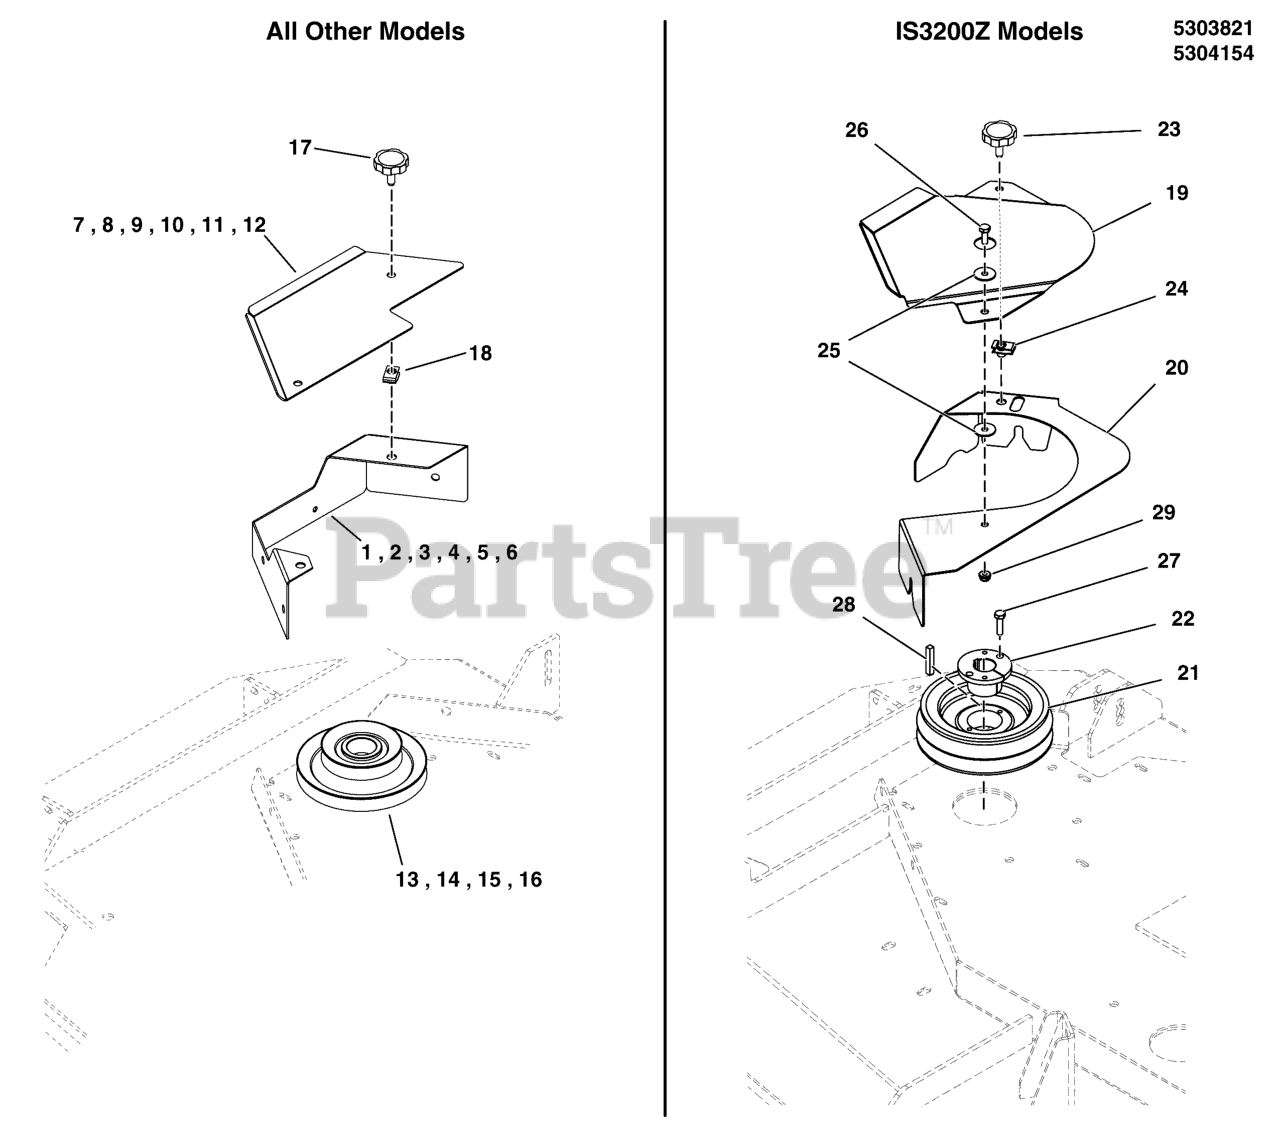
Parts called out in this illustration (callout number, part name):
1	GUARD, DECK, 61", TURBO-PRO - BLK
2	GUARD, DECK, 61/200XT, FASTVAC - BLK
3	WELD, DECK GUARD, COMM BLWR - BLK
4	GUARD, DECK, 2100-52" - BLK
5	GUARD, DECK 48/52 - BLK
6	WELD, PULLEY GUARD, 800-61, BLOWER - BLK
7	PLATE, TOP GUARD, 61" - BLK
8	GUARD, BELT, 61", 2000 FASTVAC - BLK
9	BELT SHIELD, 61" COMM BLWR - BLK
10	PLATE, TOP GUARD, 2100-52" - BLK
11	PLATE, TOP GUARD, 52 - BLK
12	SHIELD, BELT, 800-61, BLOWER - BLK
13	DOUBLE PULLEY, DECK, 61" TP
14	PULLEY, DOUBLE, DH4600, 5.95 OD TAPERED
15	PULLEY, DOUBLE, 52" DECK
16	DOUBLE PULLEY, DECK, 800-61", T-MAX
17	KNOB, 5/16-18 X 1.00, ROSETTE, BLK
18	BODY CLIP, 5/16-18-7GA MATERIAL
19	SHIELD, BELT, 3200-61", BLOWER - BLK
20	GUARD, DECK PULLEY, 3200-61" - BLK
21	PULLEY, DOUBLE, 5.95/6.43 OD, IS3200
22	BUSHING, TAPERED HUB
23	KNOB, 5/16-18 X 1.00, ROSETTE, BLK
24	BODY CLIP, 5/16-18-7GA MATERIAL
25	WASHER, 1/4 FENDER
26	BOLT, 1/4-20 X 3/4 GD5 CZ
27	BOLT, 1/4-20 X 1" GD5 CZ
28	KEY 1/4 SQ X 1 1/2 LONG
29	NUT, 1/4-20 HEX NYLOCK FLANGE
